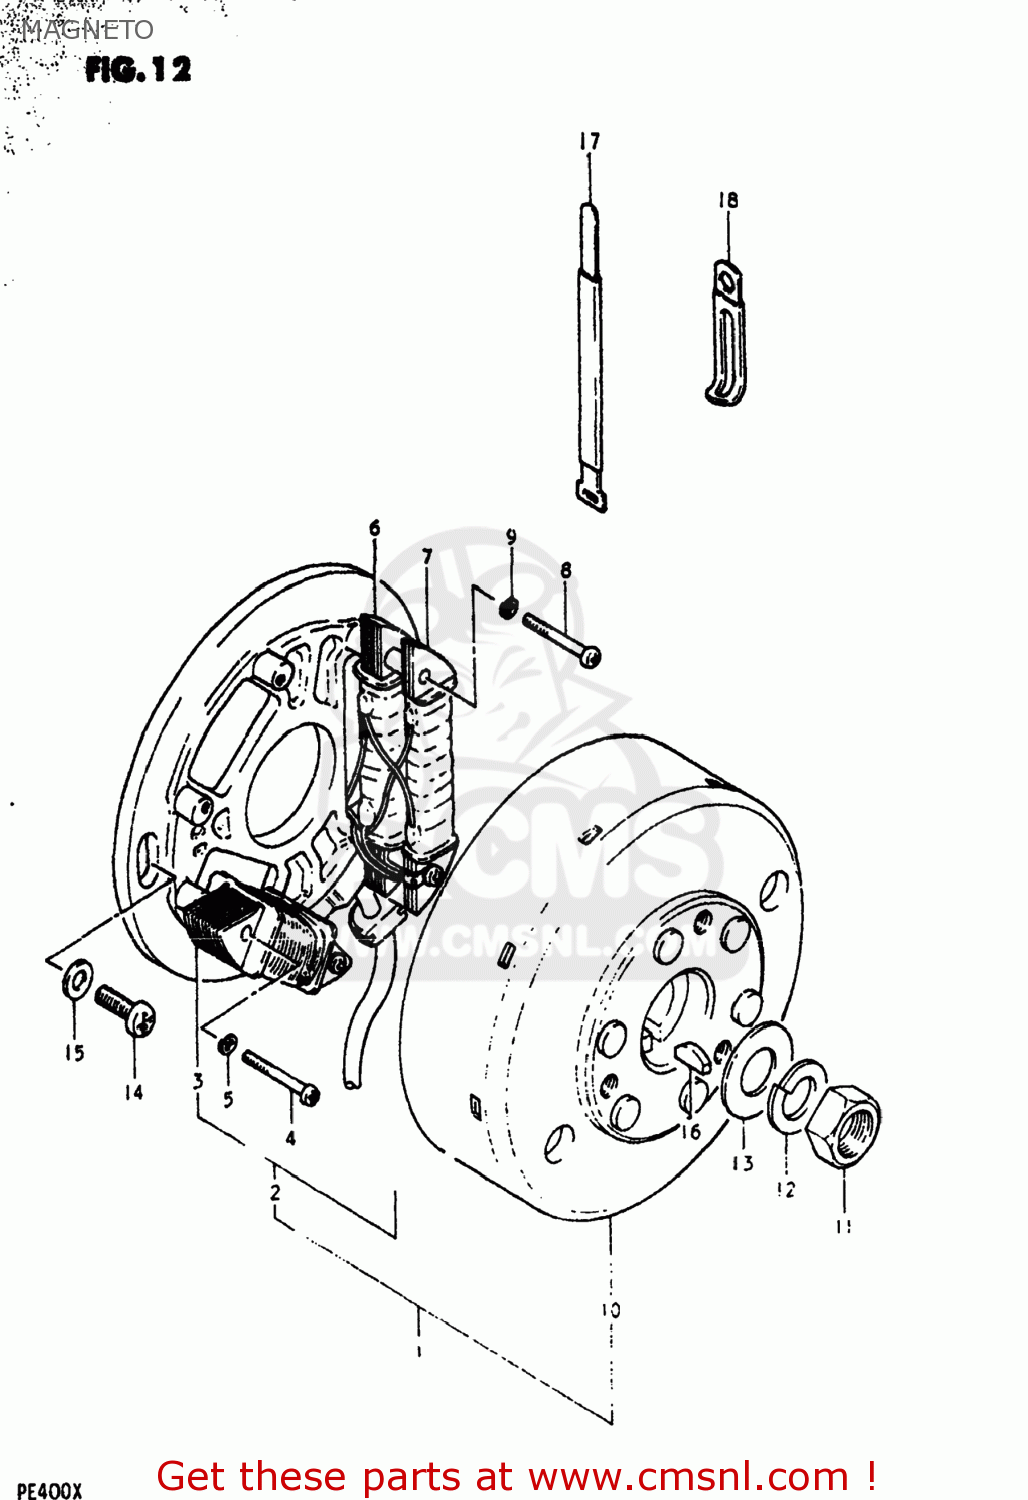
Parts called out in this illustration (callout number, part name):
1	MAGNETO ASSEMBLY
2	STATOR ASSEMBLY
3	COIL,LIGHTING
4	SCREW (4X30)
5	LOCK WASHER
6	COIL,PRIMARY
7	COIL,PULSER
8	SCREW
9	LOCK WASHER
10	ROTOR ASSEMBLY
11	NUT (10MM)
12	LOCK WASHER
13	WASHER
14	SCREW
15	WASHER
16	KEY 4MM
17	CLAMP L:110
18	CLAMP
